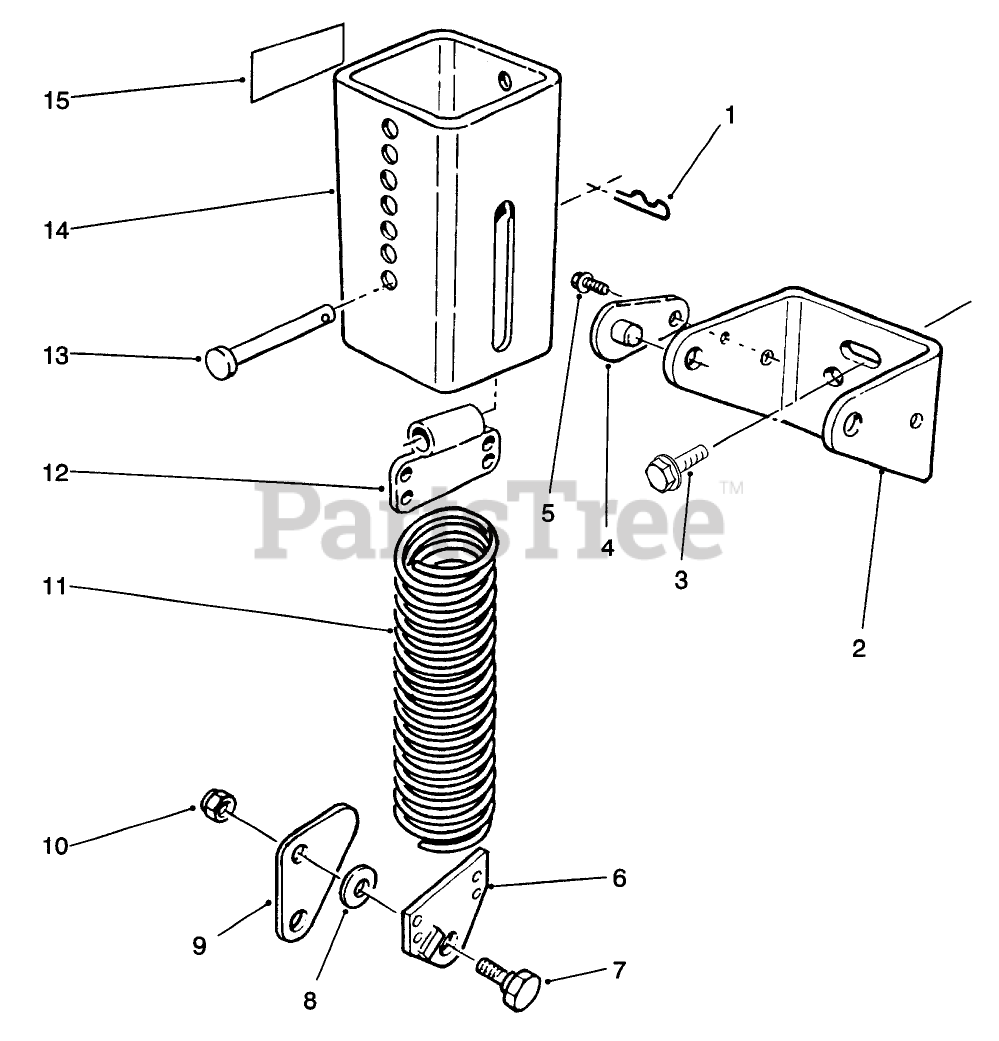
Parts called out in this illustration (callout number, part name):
1	PIN-HAIR
2	Bracket-Support
3	SCREW-HHF
4	PIN-LOCK
5	SCREW
6	End Spring
7	BOLT-SHOULDER
8	WASHER-FLAT
9	Link
10	NUT-LOCK, NI
11	Spring-Extension
12	End Spring
13	PIN-CLEVIS
14	Asm-Spring Cover
15	DECAL-WARNING
